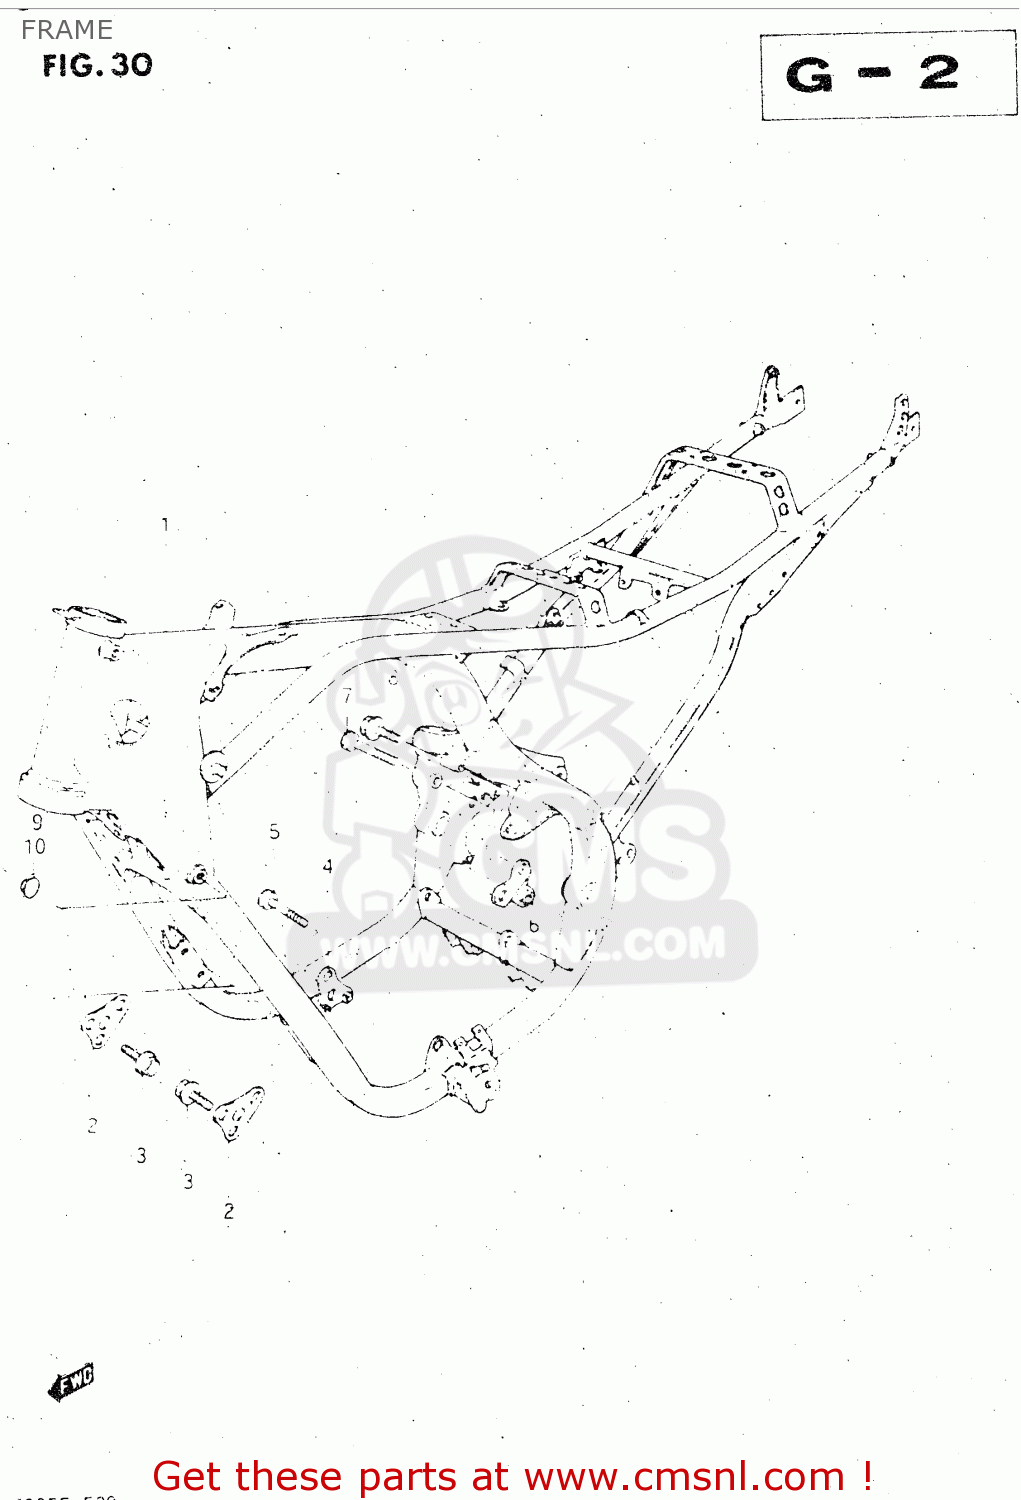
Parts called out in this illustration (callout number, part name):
1	FRAME
2	PLATE,ENGINE MOUNTING NO
3	BOLT
4	PLATE,ENGINE MOUNTING NO
5	BOLT
6	PLATE,ENGINE MOUNTING NO.4
7	BOLT
8	BOLT
9	PLUG
10	PLUG
